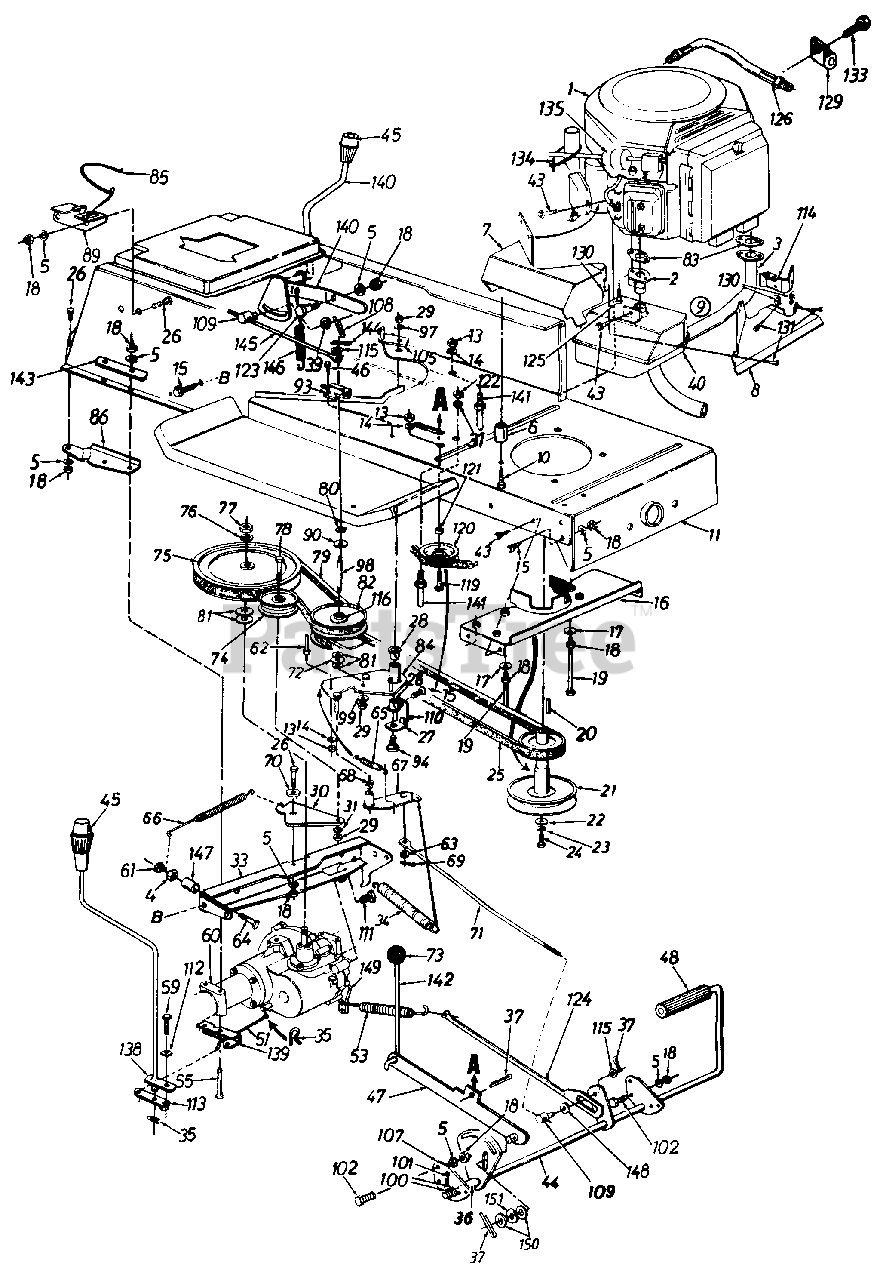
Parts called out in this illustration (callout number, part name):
1	Engine
2	Inlet Tube Ass'y.
3	Formed Tube Ass'y.
4	Hex Nut 5/16-24 Thd.
5	L-Wash. 5/16" I.D.
6	Spacer 1.25" Lg.
7	Muffler Heat Shield
8	Front Heat Shield
9	Muffler Ass'y. Comp.
10	Hex L-Wash. Tap Scr. 3/8-16 Thd.
11	Lower Frame Ass'y.
13	Hex Nut 1/4-20 Thd.
14	L-Wash. 1/4" I.D.
15	Hex Wash. TT-Tap Scr. 5/16-18 x.62" Lg.
16	Belt Guard Brkt. Ass'y.
17	Bell-Wash. .345" I.D. x .88"
18	Hex Nut 5/16-18 Thd.
19	Hex Bolt 5/16-18 x 4.0"
20	Sq. Key 1/4" x 1/4" x 2.00"
21	Engine Pulley
22	Fl-Wash. 7/16" I.D. x 1.25"
23	L-Wash. 7/16" I.D.
24	Hex Bolt 7/16-20 x 1.50" Lg.
25	Variable-Speed Belt
26	Hex Bolt 5/16-18 x 75" Lg.
27	Bearing Shaft Bracket Ass'y.
28	Flanged Nyliner Brg. 5/8" I.D. x .88" Lg.
29	Hex Nut 3/8-24 Thd.
30	Idler Bracket
31	L-Wash. 3/8" l.D.
33	Transaxle Support Brkt.
34	Ext. Spring .94" O.D. x 7.58"
35	Inter. Cotter Pin
36	Spacer.63" l.D.
37	Cotter Pin 1/8' Dia. x 1.0" Lg.
39	FL-Wash. .51" I.D. x .75"
40	Exhaust Muffler Sub. Ass'y.
43	Hex Wash. Hd. S-Tap Scr. 1/4-20 x .50" Lg.
44	Clutch/Brake Pedal Ass'y.
46	Hex Wash. Hd. B-Tap Scr. #10 x .5" Lg.
47	Parking Brake Lockout Brkt. Ass'y.
48	Foot Pad
51	Shift Lever Rod
53	Ext. Spring 3.6"
55	Hex Bolt 5/16-18 x 3.25"
59	Hex Bolt 1/428 x .62" Lg.
60	Transaxle Complete
61	Hex L-Nut 1/4-20 Thd.
62	Belt Guard Pin '/4-20 Thd.
63	Fl-Wash. .34 I.D. x .68" 0 D.
64	Hex Wash. TT-Tap Scr. 1/4-20 x 1 .75
65	Ext. Spring 2.59" Lg.
66	Ext. Spring .5" O.D. x 4.35"
68	Flanged Bearing
69	Cotter Pin 3/32" Dia.
70	Shoulder Spacer .27" Lg.
71	Speed Control Link
72	Truss Bearing .56 Dia. x 1 .25
74	Fl-ldler Pulley 3.25" x .75"
76	L-Wash. 1/2" I.D.
77	Hex Jam Nut 1/2-20 Thd.'
78	Hex Bolt 3/8-24 x 1.75" Lg.
79	Variable Speed Belt
80	Snap Ring .56" Dia.
81	Fl-Wash. .56" I.D. x 1.0" O.D.
82	Variable Speed Pulley Ass'y. 5" O.D.
83	Gasket
90	Teflon Washer .565" I.D.
93	Safety Switch
94	Shld. Bolt 3/8-24 x 3.12" Lg.
97	Bell-Wash. .38" I.D. x .88"
99	Bell-Wash. .39" I.D. x 1.12"
100	Fl-Wash. .64" I.D. x .94"
101	Cotter Pin 3/32" Dia. x 1.0"
102	Hex Wash. Hd. Scr. 5/16-18 x.62" Lg.
105	Belt Guard
107	Pedal Bracket
108	Cotter Pin 3/32" Dia. x .75"
109	Ferrule
110	Hex Bolt 5/16-18 x 1.0" Lg.- (Gr. 5)
111	Hex Wash. Tap Scr. 5/16-18 x 1.25" Lg.
112	Bell-Wash. .265" I.D. x .75"
113	Shift Lever Link Ass'y.
114	Front Hea,t Shield Ext.
115	Fl-Wash. 385" l.D. x .62"
116	Needle Brgs.
119	Hex Bolt 3/8-16 x 1.25" Lœ
120	Fl-ldler w/Flanges 2.75" O.LJ.
121	Fl-Wash. .39" I.D. x 1.12" O.D.
122	Hex Nut 3/8-16 Thd.
123	Shld. Bolt 437" Dia. x .162"
124	Brake Rod Ass'y
125	Hex Bolt w/Washer
130	Speed Nut #10-24 Thd.
131	Hex AB-Tap Scr. #10 x .5 Lg.
133	Hex Cap Scr. M6 x 17 MM
134	Cable Tie
138	Shift Lever Ass'y.
139	Shift Lever Support Brkt.
140	Speed Selector Lever Ass'y.
141	Belt Guard Pin
142	Brake Lockout Rod
144	Cotter Pin 1/8" x 3/4" Lg.
145	Speed Selector Rod
146	Ext. Spring 3.97" Lg.
147	Spacer.326" I.D. x 47"
148	Fl-Wash. 5/8" l.D. x 1.25"
149	Actuating Arm
150	Fl-Wash. .385" I.D. x.87" O.D.
151	Wave Wash. 38" l.D. x .75"
